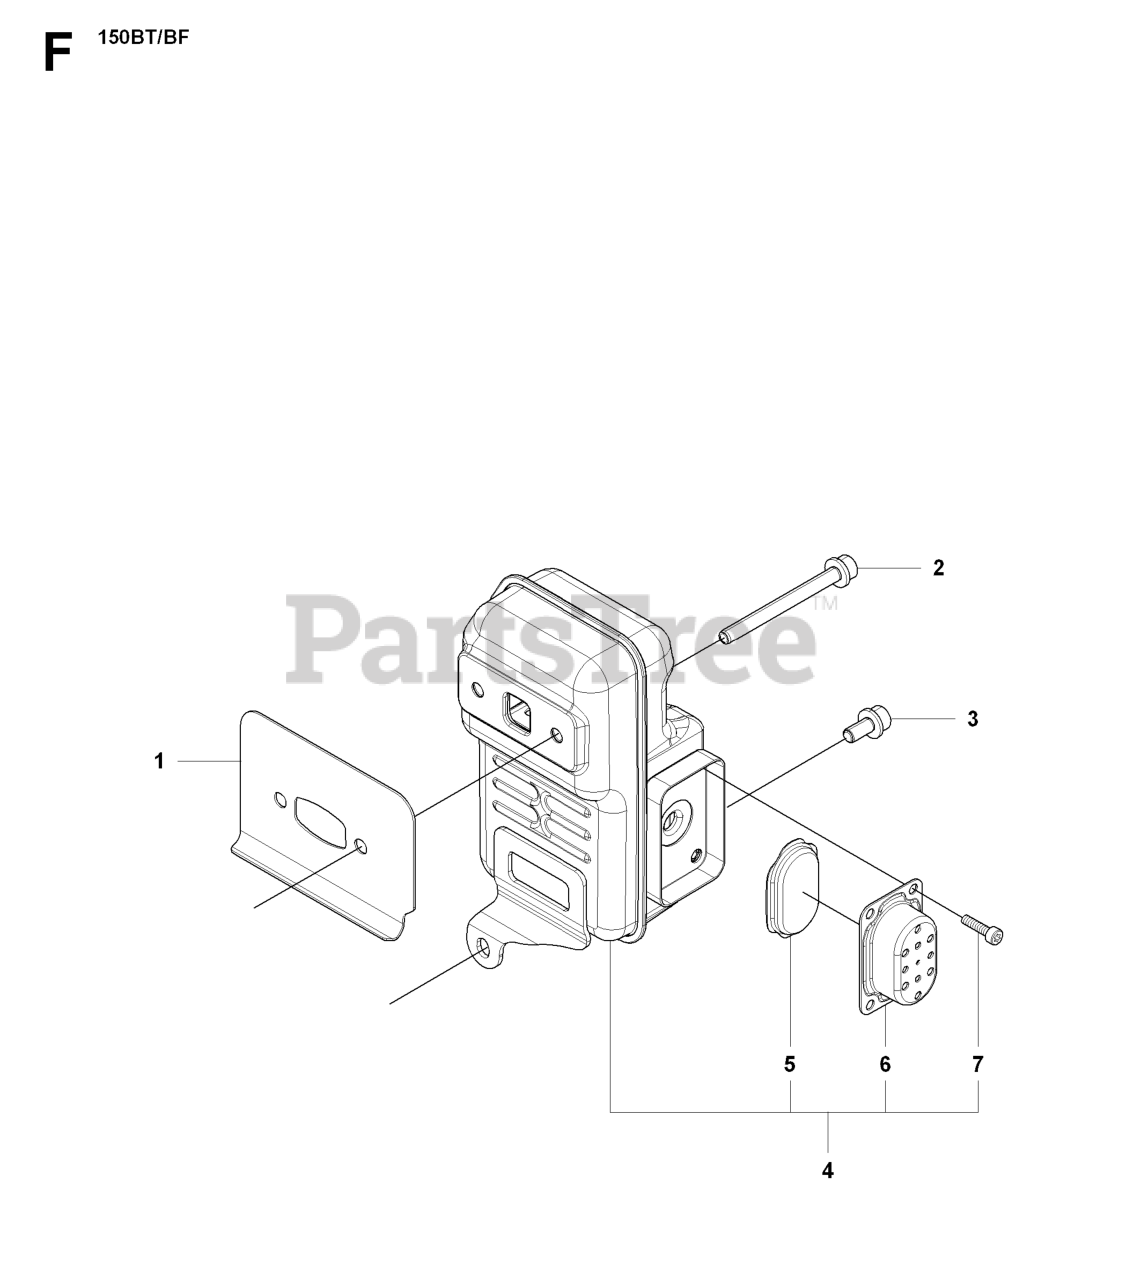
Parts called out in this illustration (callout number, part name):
1	GASKET
3	RP_BOLT
4	MUFFLER ASSY
5	SPARK ARRESTOR SCREEN
6	EXHAUST DUCT
